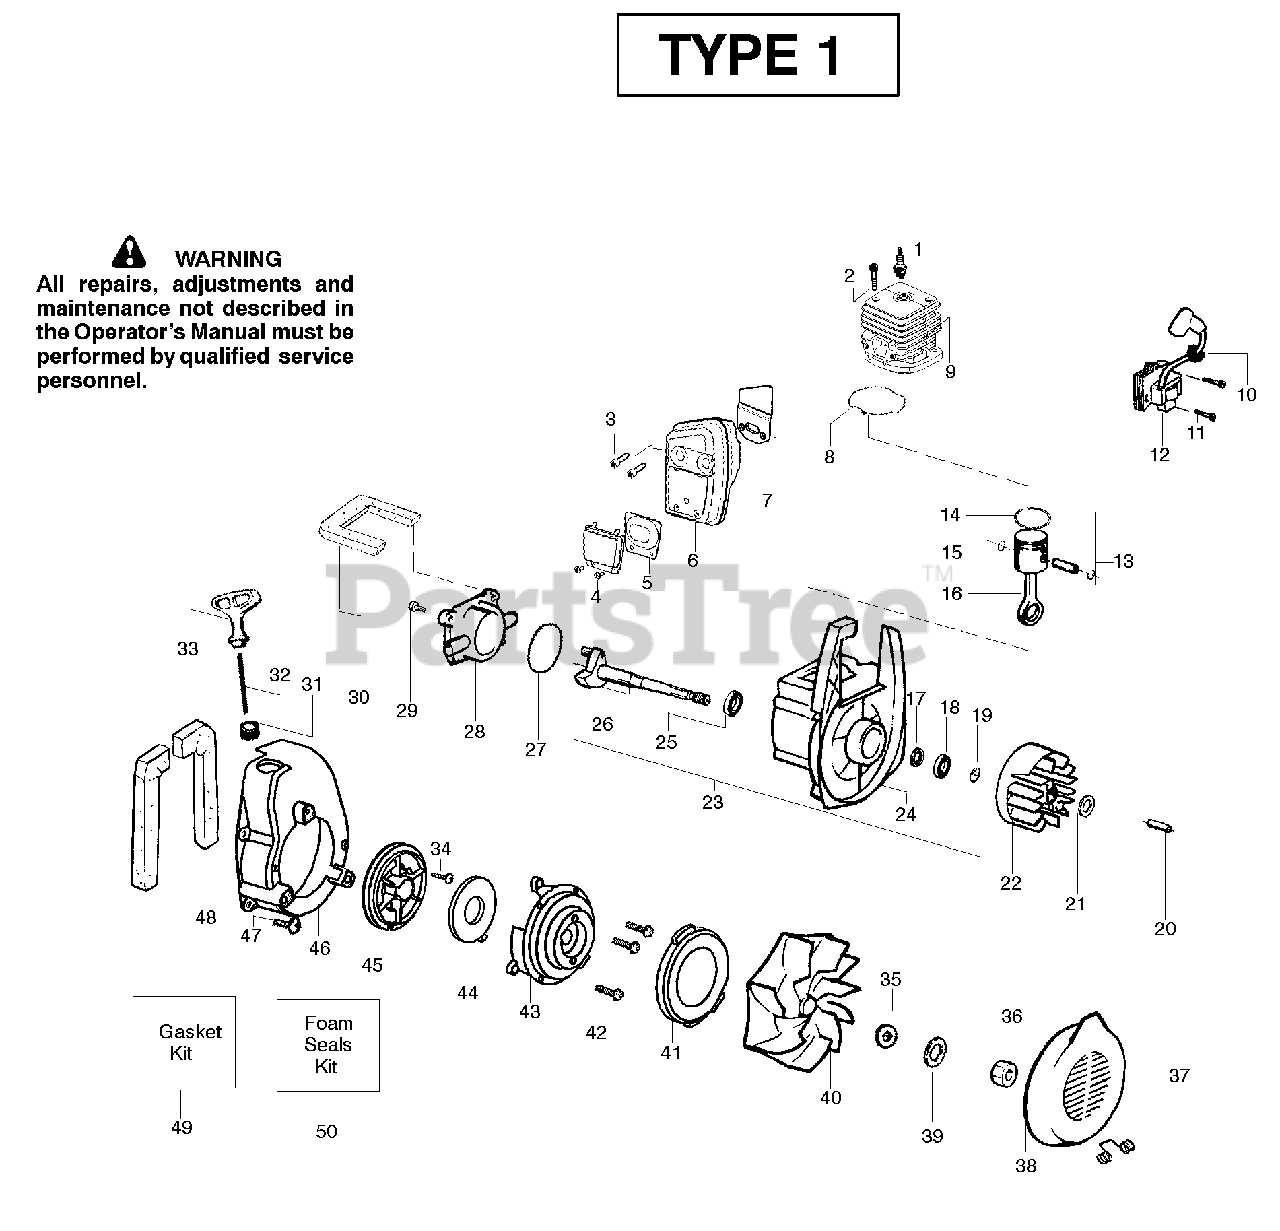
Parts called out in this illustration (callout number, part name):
1	Spark Plug (RCJ-6Y)
3	Screw-Muffler-Internal
5	Kit-Spark Screen
6	Kit-Muffler
7	Gasket-Baffle (kit)
8	Gasket-Cylinder (kit)
9	Kit-Cylinder
10	Grommet-Ign. Module
11	Screw-Ignition Module
12	Ignition Module
13	Kit-Piston
14	Piston Ring
15	Retainer-Piston Pin
16	Assy-Connecting Rod
17	Seal-Crankcase
18	Bearing-Outer
19	Retainer Ring-C’chaft
20	Spacer-Flywheel
22	Assy-Flywheel
23	Assy-Crankcase/Crank shaft
24	Assy-Crankcase
25	Bearing-Inner
26	Assy-Crankshaft
27	O-ring-C/case (kit)
28	Cover-Crankcase
29	Screw
30	Foam-219mm (kit)
31	Eyelet-Flange
32	Kit-Rope
33	Handle-Starter
35	Washer-Belleville
37	Spring-Return Cover
40	Assy-Impeller
43	Housing-Pulley
44	Spring-Starter
45	Kit-Starter Pulley
47	Screw
48	Foam-182mm (kit)
49	Kit-Gasket
50	Kit-Foam Seals
